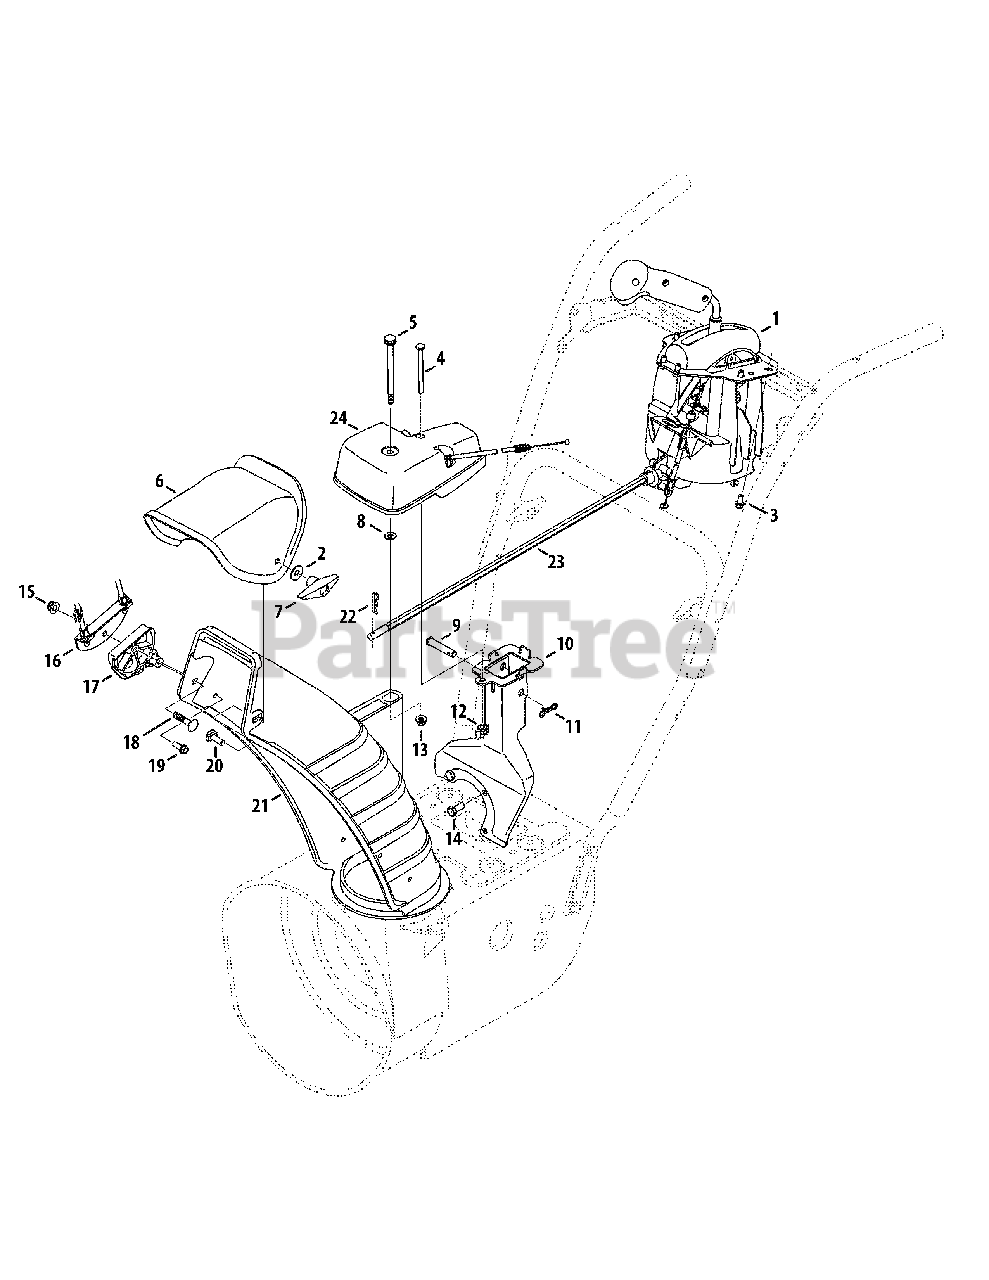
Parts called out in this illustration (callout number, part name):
1	Chute Control, 4-Way
2	Washer, Flat, .349 x .879
3	Hex Washer Screw, 1/4-15 x .50
4	Hex Head Screw, 1/4-20 x 3.00
5	Screw, Shoulder, .312 x 3.5 x 1/4-20
6	Upper Chute
7	Wing Knob, 5/16-18
8	Washer, Flat, .25 x .630
9	Clevis Pin, 3/8 x 1.87
10	Chute Support Bracket
11	Bow-Tie Cotter Pin
12	Wing Nut, 1/4-20
13	Flange Lock Nut, 1/4-20
14	Hex Lock Screw, 5/16-24 x .750
15	Flange Lock Nut, 5/16-18
16	Cable Bracket
17	Chute Tilt Cable Guide
18	Carriage Bolt, 5/16-18 x 1.50
19	Hex Washer Screw, 1/4-15 x .750
20	Carriage Bolt, 5/16-18 x 1.00
21	Lower Chute, 5.0
22	Internal Cotter Pin
23	Chute Rod, 3/8 Hex
24	Gearbox Assembly, Chute Rotation
